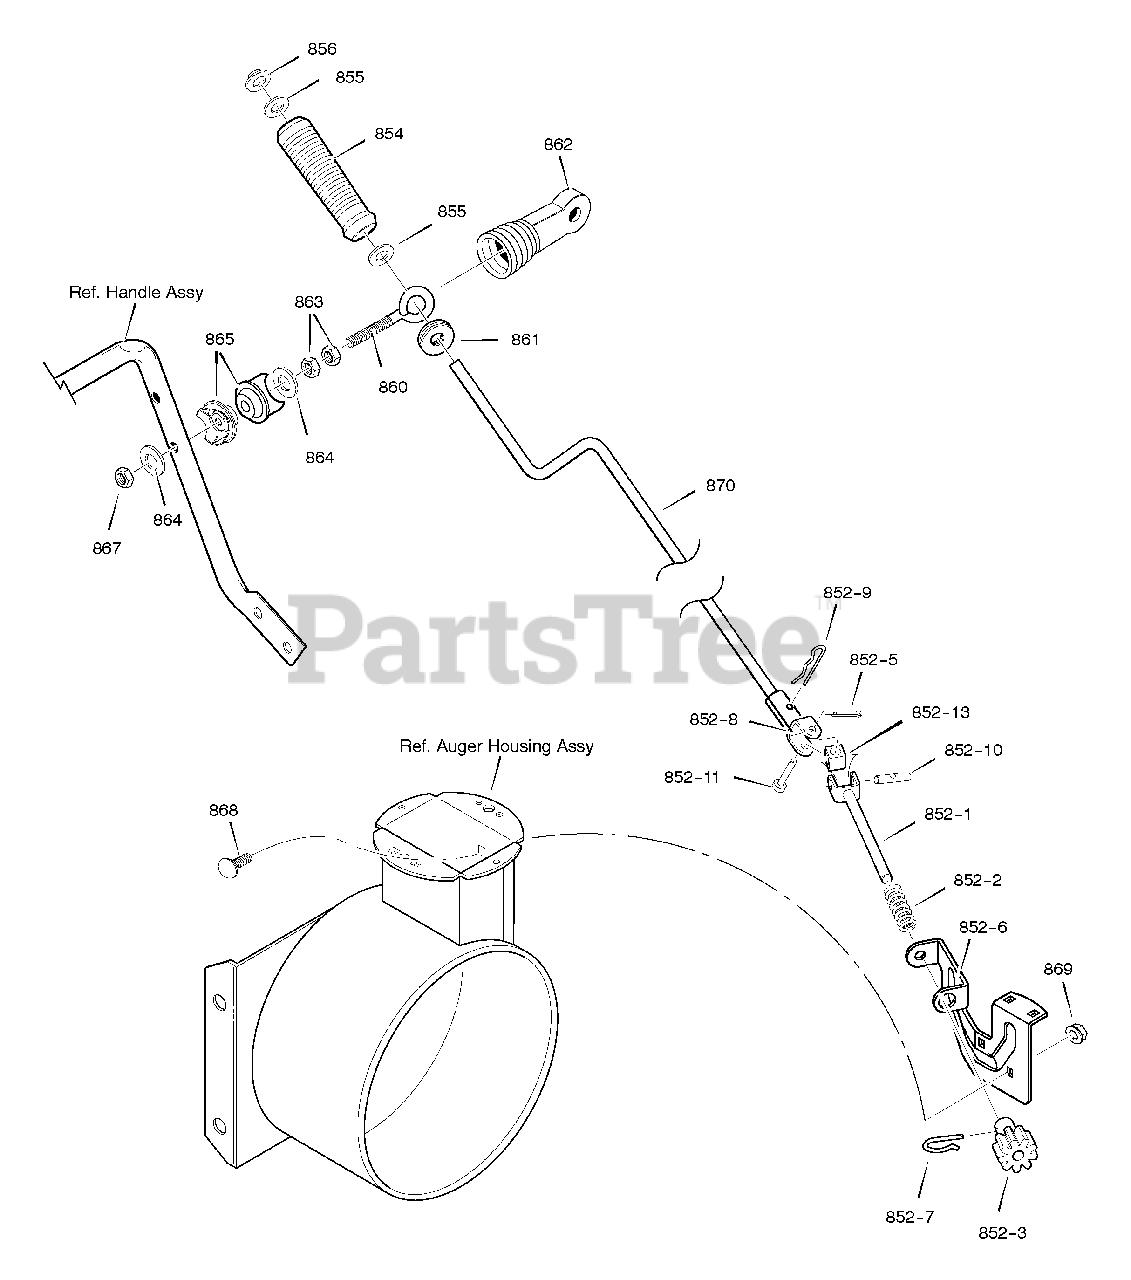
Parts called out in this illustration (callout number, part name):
852-1	ASSEMBLY, YOKE & ROD
852-2	SPRING
852-3	GEAR, CHUTE ROTATION 9T
852-5	PIN, COTTER
852-6	BRACKET, CHUTE GEAR
852-7	PIN, HAIR
852-8	ASSEMBLY, YOKE ADAPTER YZ
852-9	PIN, HAIR
852-10	PIN, UNIVERSAL JOINT
852-11	PIN, CLEVIS
852-13	HOUSING, UNIVERSAL
854	KNOB, SLEEVE
855	FLATWASHER
856	NUT, PUSH ON 3/8"
860	EYE BOLT 3/8-16X6.50
861	GROMMET, EYE BOLT
862	BOOT, EYE BOLT
863	NUT, 3/8-16 HEXJAM
864	FLATWASHER .406X.81X.066
865	ADAPTER, BOOT
867	NUT, 3/8-16 HEXNYL
868	BOLT, CARRIAGE 1/4-20 X 0.75
869	NUT, 1/4-20
870	CRANK, ASSY CHUTE
